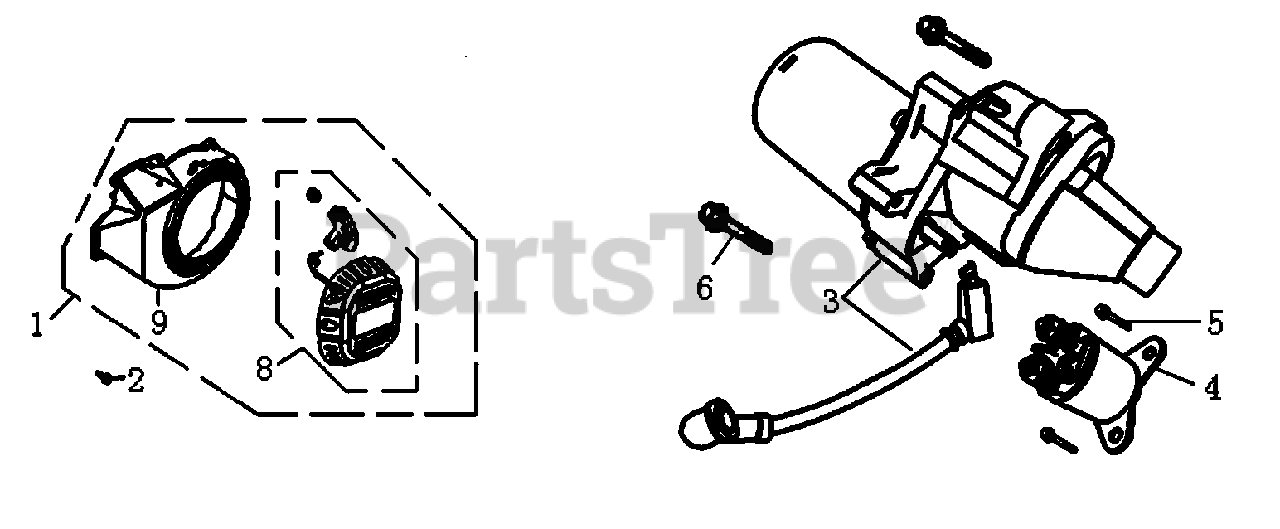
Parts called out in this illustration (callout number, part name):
1	STARTER ASSY.
2	BOLT, FLANGE
3	MOTOR, STARTER
4	CONTACTOR ASSY.
5	BOLT, WASHER
6	BOLT, FLANGE
8	COVER, RECOIL
9	HOUSING, BLOWER
